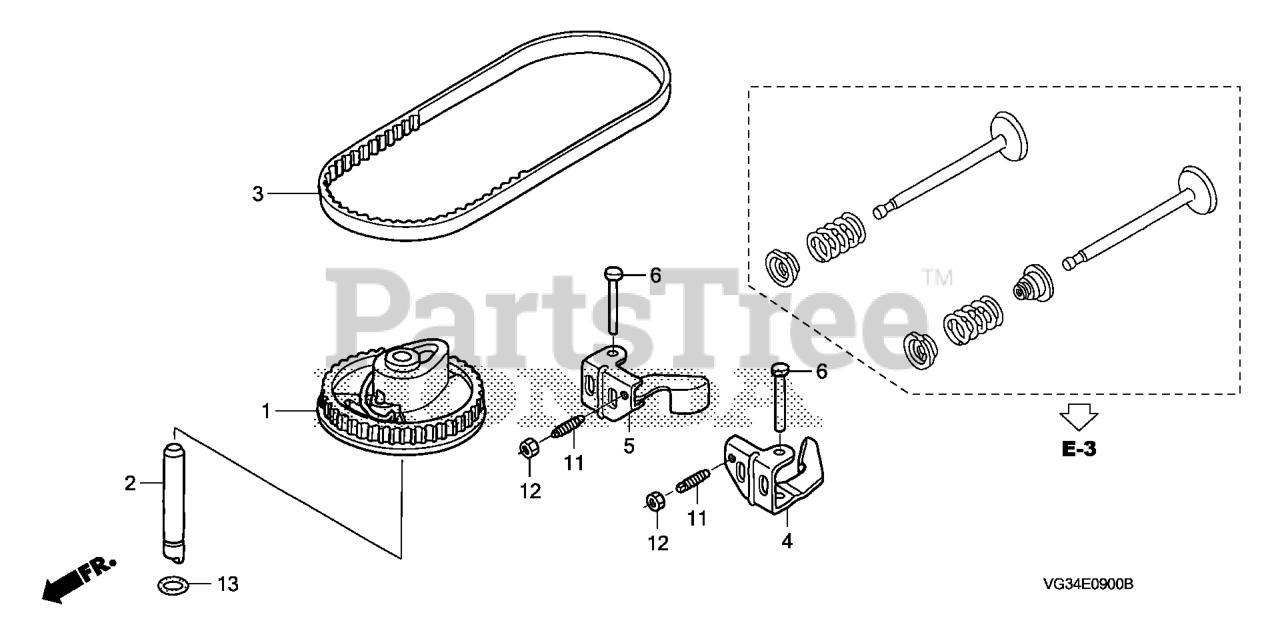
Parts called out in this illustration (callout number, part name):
1	PULLEY, CAMSHAFT
2	SHAFT, CAM PULLEY
3	BELT, TIMING (84HU6 G-200)
4	ARM, IN. VALVE ROCKER
5	ARM, EX. VALVE ROCKER
6	SHAFT, ROCKER ARM
11	SCREW, TAPPET ADJ.
12	NUT, TAPPET ADJ.
13	O-RING (6.8X1.9) (ARAI)
